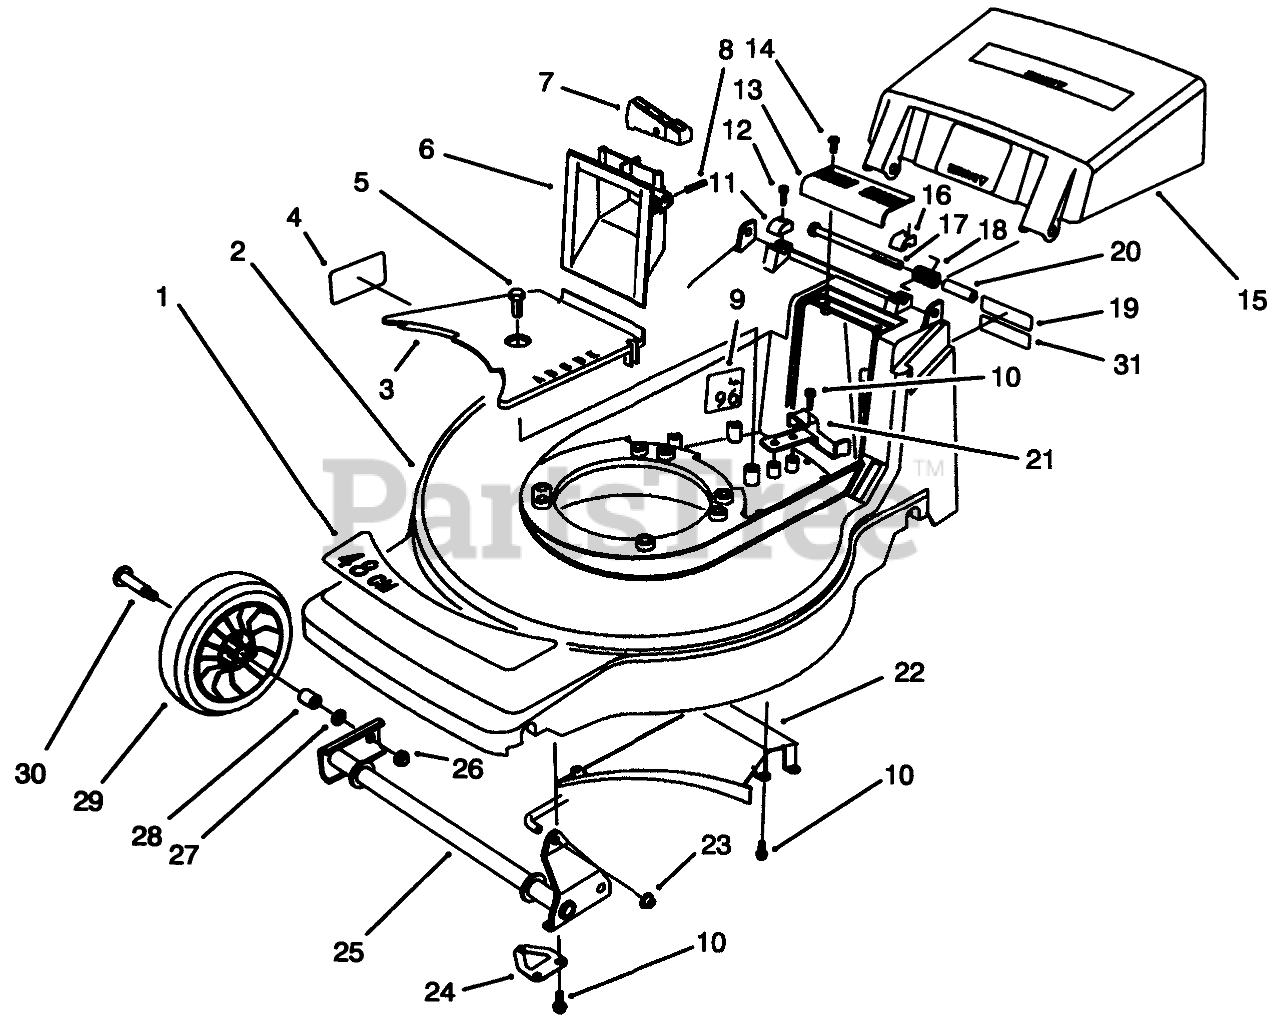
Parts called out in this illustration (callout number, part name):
1	DECAL - DECK 48 CM
2	Housing-48cm (Incl. Ref. #4)
3	BELT COVER
4	Decal Danger
5	SCREW-HWHTF
6	GRIP - LOWER
7	TRIGGER - HOC
8	PIN-SPIRAL
9	Decal-Noise Rating
10	SCREW-HWH
11	CAP-HINGE BOLT, RH
12	SCREW-HSH
13	GRIP-UPPER
14	SCREW-PPH, PLASTITE
15	Door Discharge
16	CAP-HINGE BOLT, LH
17	SCREW-HH
18	SPRING-DOOR
19	DECAL FRENCH REGUL.
20	SPACER-DOOR
21	REAR BELT GUIDE
22	Ramp-Discharge
23	NUT-PUSH
24	SHAFT RETAINER ASM
25	FRONT PIVOT WA
26	NUT-HEX
27	WASHER
28	BUSHING
29	Wheel & Tire Assembly (Incl. Ref. #28)
30	BOLT-WHEEL
31	Decal-Power Rating
